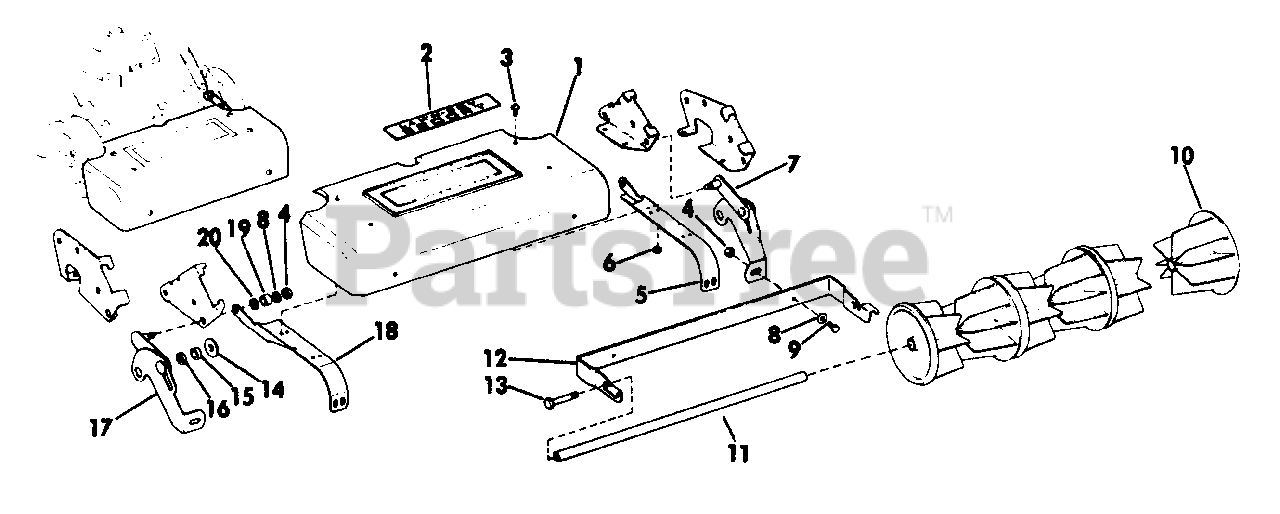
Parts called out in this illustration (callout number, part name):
1	Roller Cover & Decal Assembly
5	Cover Hinge-Right
7	Roller Link Assembly-Left
12	Carrier Strip
15	Spacer-Wheel-Red
16	Spacer-Wheel Bracket-Red
17	Roller Link Assembly-Right
18	Cover Hinge-Left
19	Spacer-Silver
20	Spacer-Hinge-Silver
